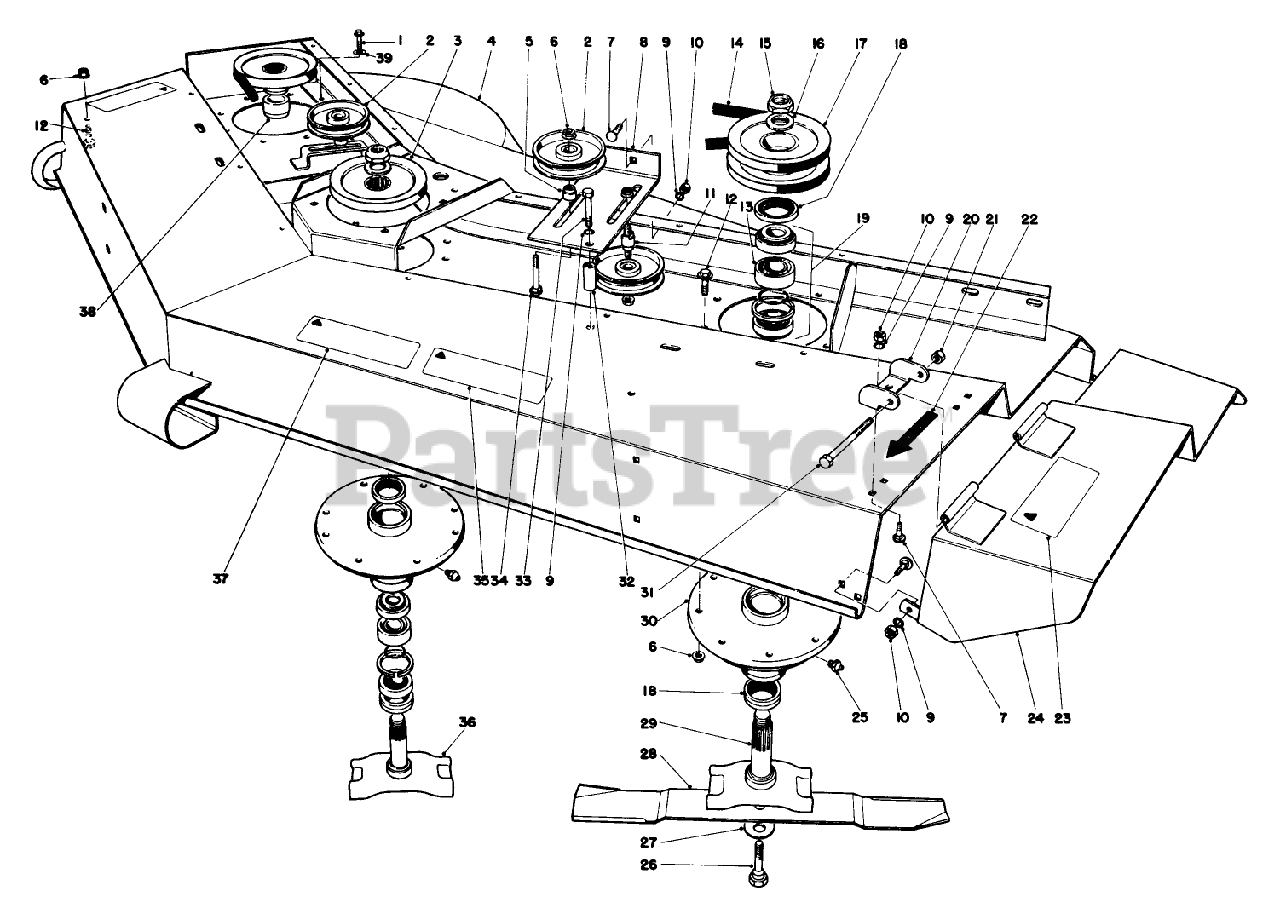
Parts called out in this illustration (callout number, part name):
1	SCREW-HHF
2	PULLEY-IDLER
3	PULLEY AND HUB ASM
4	Cutter Deck
5	SPACER-IDLER PULLEY
6	NUT-HF
7	SCREW-CARR
8	Idler Mount L.H.
9	WASHER-LOCK
10	NUT-HEX
11	STUD-IDLER
12	SCREW-HHF
13	Spacer Matched Set
14	V-BELT
15	NUT-LOCK, NI
16	WASHER-THRUST
17	PULLEY-L.H. W.A.
18	SEAL-OIL
19	BEARING KIT (MATCHED SET)
20	HINGE BRKT
21	NUT-HEX
22	DECAL - BLADE LINE
23	DECAL-CAUTION, DEFLECTOR
24	Deflector
25	FITTING-GREASE
26	CAPSCREW
27	WASHER-BELLEVILLE
28	BLADE-STANDARD, LH, 25IN
29	OUTER SPINDLE WA
30	Spindle Housing
31	SCREW-HH
32	SPACER-IDLER MOUNT
33	SCREW-HH
34	SCREW-CARR
35	DECAL-CAUTION, BLADE
36	Spindle Ctr.
37	Decal-Caution
38	Spacer R.H.Spindle
39	WASHER-FLAT
